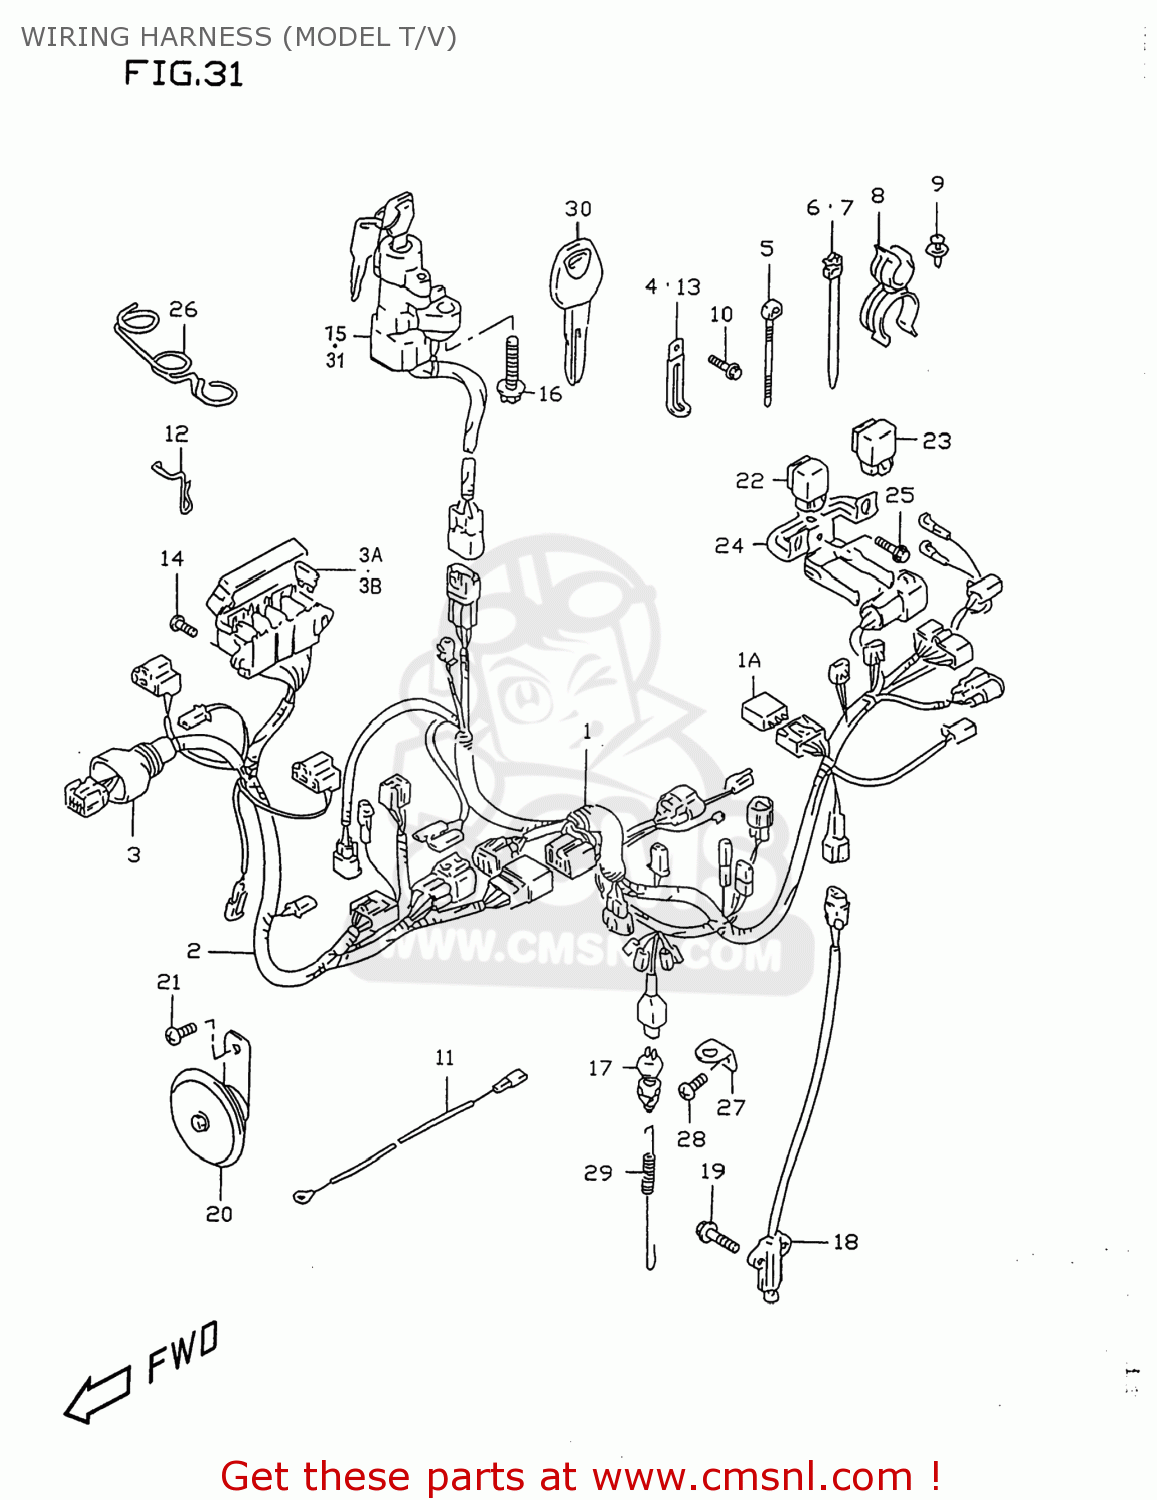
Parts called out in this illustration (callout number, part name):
1	HARNESS,WIRING NO.1
1A	DIODE(STANLEY DE8804)
2	HARNESS,WIRING NO.2
3	COVER,SPEEDOMETER COUPLER
3A	FUSE(10A)
3B	FUSE(15A)
4	CLAMP(L:45)
5	CLAMP(L:95)
6	CLAMP(L:120)
7	CLAMP(L:165)
8	CLAMP
9	CLIP(BLACK)
10	BOLT
11	WIRE,OIL PRESSURE SWITCH LEAD
12	STOPPER,FUSE BOX
13	CLAMP(L:80)
14	SCREW
15	LOCK ASSY,STEERING
16	BOLT(8X20)
17	SWITCH ASSY,STOP LAMP
18	SWITCH ASSY,SIDE STAND WARNING
19	BOLT 6X20
20	HORN ASSY
21	SCREW(8X14)
22	RELAY ASSY
23	RELAY ASSY
24	BRACKET,SIDE STAND RELAY
25	BOLT
26	GUIDE,WIRING HARNESS
27	BRACKET,STOP LAMP SWITCH
28	SCREW
29	SPRING
30	KEY,BLANK
